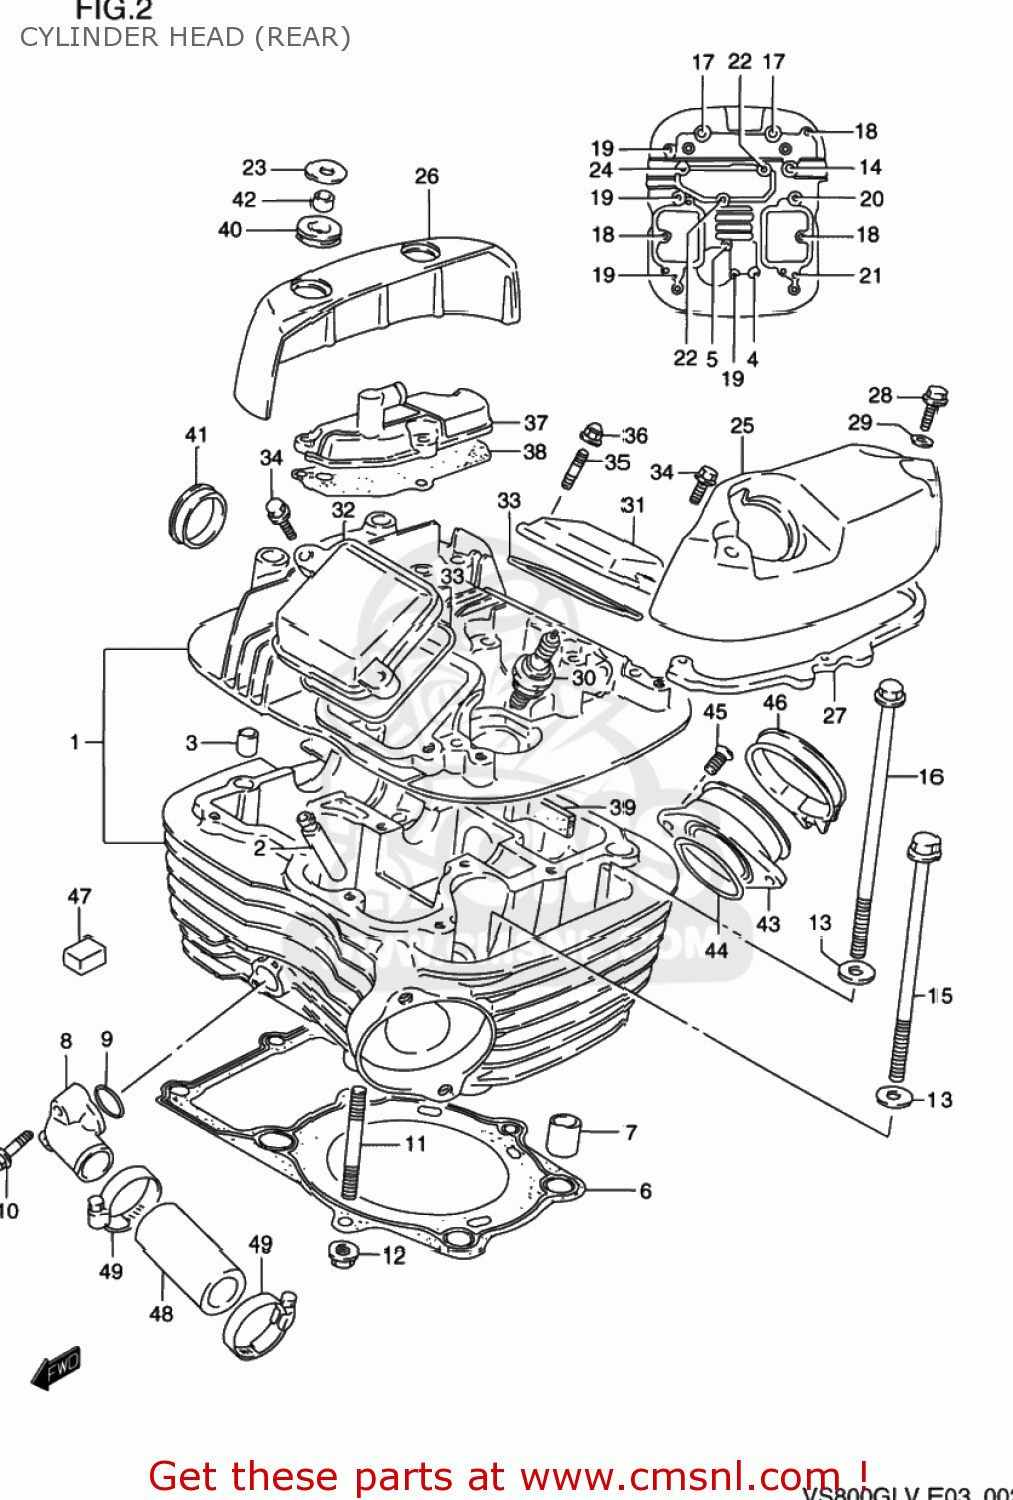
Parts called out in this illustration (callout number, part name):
1	HEAD ASSY,CYLINDER RR
2	GUIDE,VALVE
3	PIN(11X14)
4	BOLT(6X50)
5	BOLT(6X55)
6	GASKET,CYLINDER HEAD RR (NAS)
7	PIN
8	UNION,CYLINDER HEAD WATER
9	O RING(D:2.4,ID:17.8)
10	BOLT
11	BOLT,STUD
12	NUT
13	WASHER(10.5X22X2.3)
14	BOLT(8X140)
15	BOLT(10X155)
16	BOLT(10X165)
17	BOLT(8X245)
18	BOLT
19	BOLT
20	BOLT
21	BOLT
22	BOLT(6X55)
23	WASHER (8.2X24X1.6)
24	BOLT
25	CAP,CYLINDER HEAD COVER RR,L
26	CAP,CYLINDER HEAD COVER RR,R
27	CUSHION,RR,L CAP
28	BOLT
29	WASHER
30	PLUG,SPARK(DPR8EA-9)
31	CAP,INSP.INT
32	CAP,INSPECTION,EXHAUST
33	GASKET,INSPECTION CAP (NAS)
34	BOLT
35	STUD 6X16
36	NUT
37	COVER,BREATHER
38	GASKET,BREATHER COVER (NAS)
39	PLATE,HEAD COVER RR
40	CUSHION
41	PLUG
42	BUSH
43	PIPE,INTAKE,REAR
44	O-RING (D:2.4 ID:39.7)
45	SCREW
46	CLAMP
47	PAD
48	HOSE,CYLINDER HEAD JOINT
49	CLAMP
